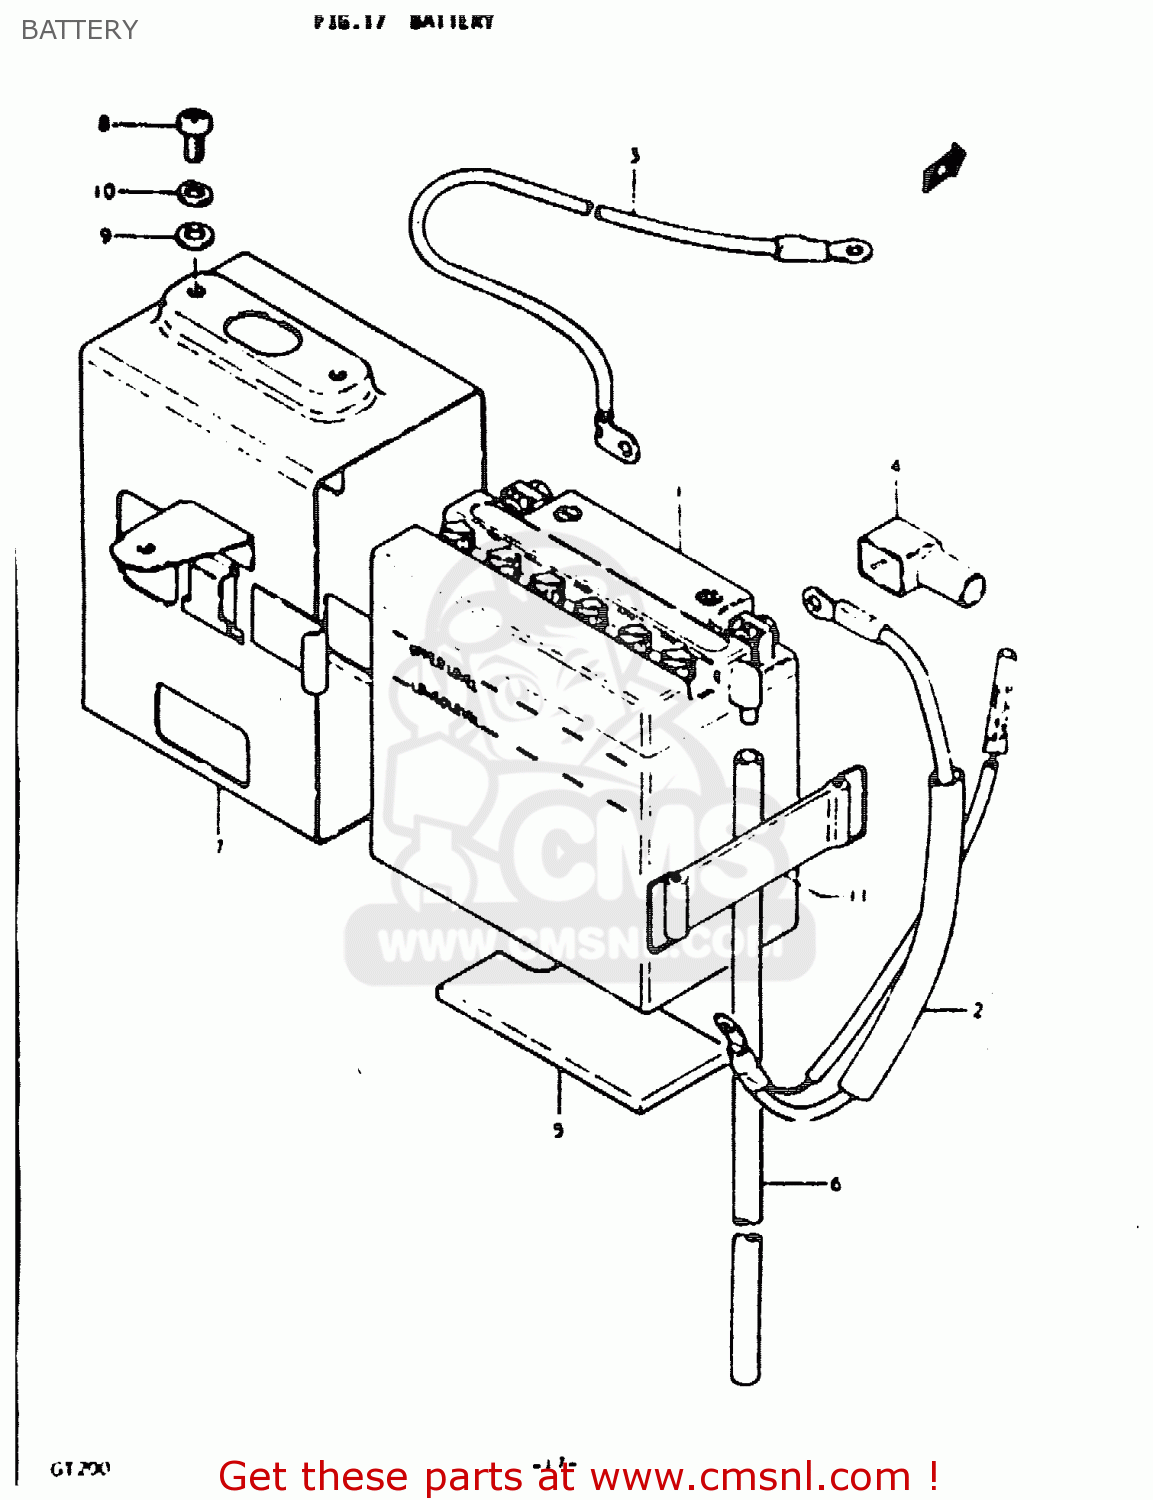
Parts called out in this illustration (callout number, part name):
1	BATTERY ASSY(YB7-A)
2	WIRE,BATTERY PLUS
3	LEAD WIRE, (-)
4	CAP, TERMINAL (+)
5	PROTECTOR,BATTERY
6	HOSE, EXHAUST
7	HOLDER, BATTERY
8	SCREW 6X12
9	WASHER
10	LOCK WASHER
11	BAND
